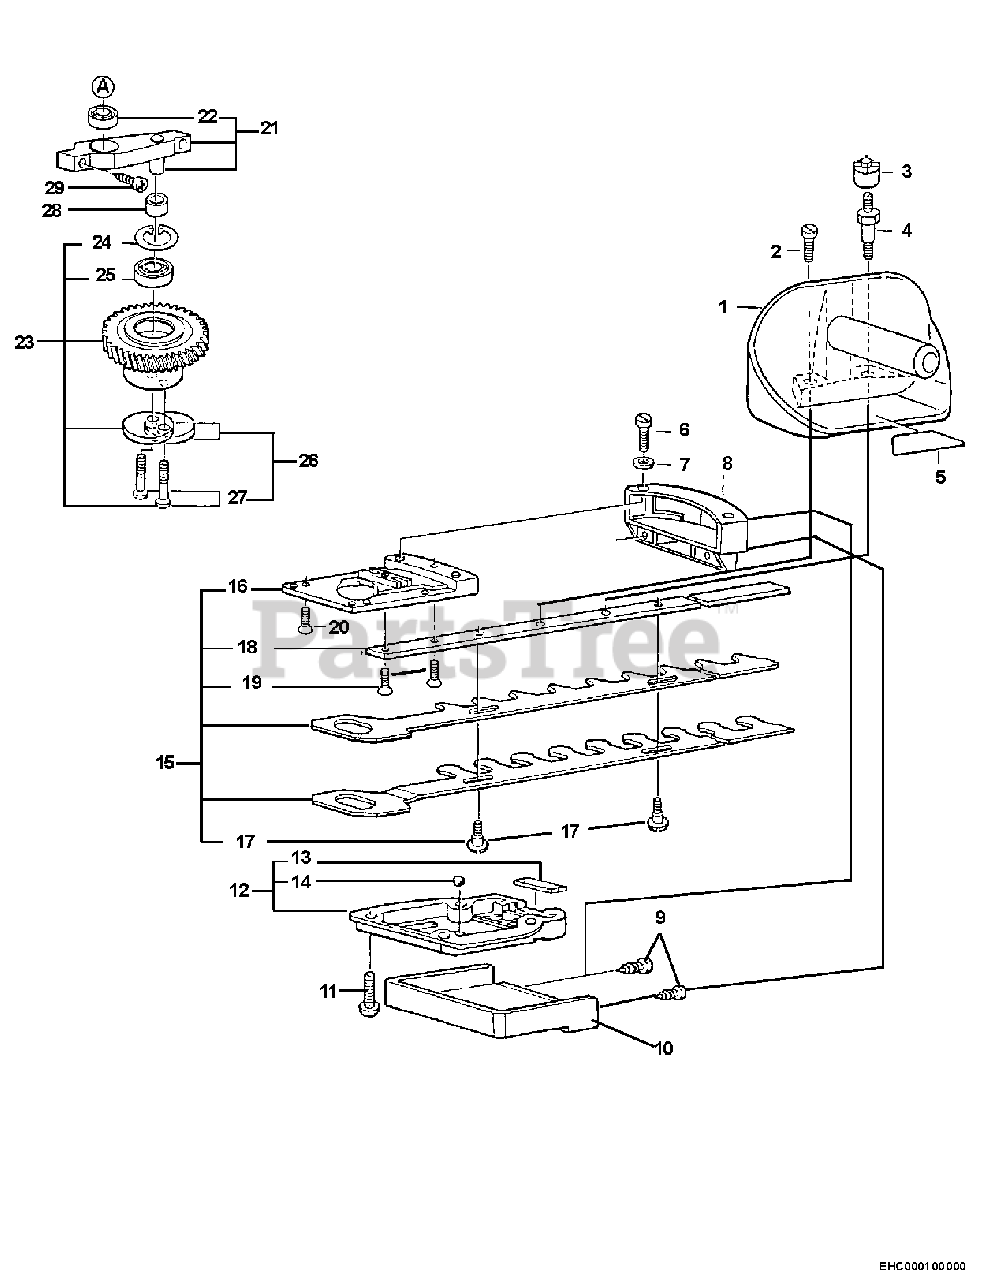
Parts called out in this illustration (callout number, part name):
1	HANDLE, AUX.
2	SCREW
3	NUT
4	DBL. END BOLT
5	LABEL - CAUTION
7	WASHER, SPRING
9	SCREW 4×16
12	LID, GEAR CASE
13	PACKING, FELT
14	BALL - 4
15	BLADE ASSY, 770 MM
16	FLANGE
17	SCREW
20	SCREW
21	FLANGE ASSY, BEARING
22	BEARING, BALL
23	GEAR ASSY
24	RING, RETAINING
25	BEARING, BALL
26	PLATE ASSY
27	DRIVING PIN
28	SPACER
29	SCREW
